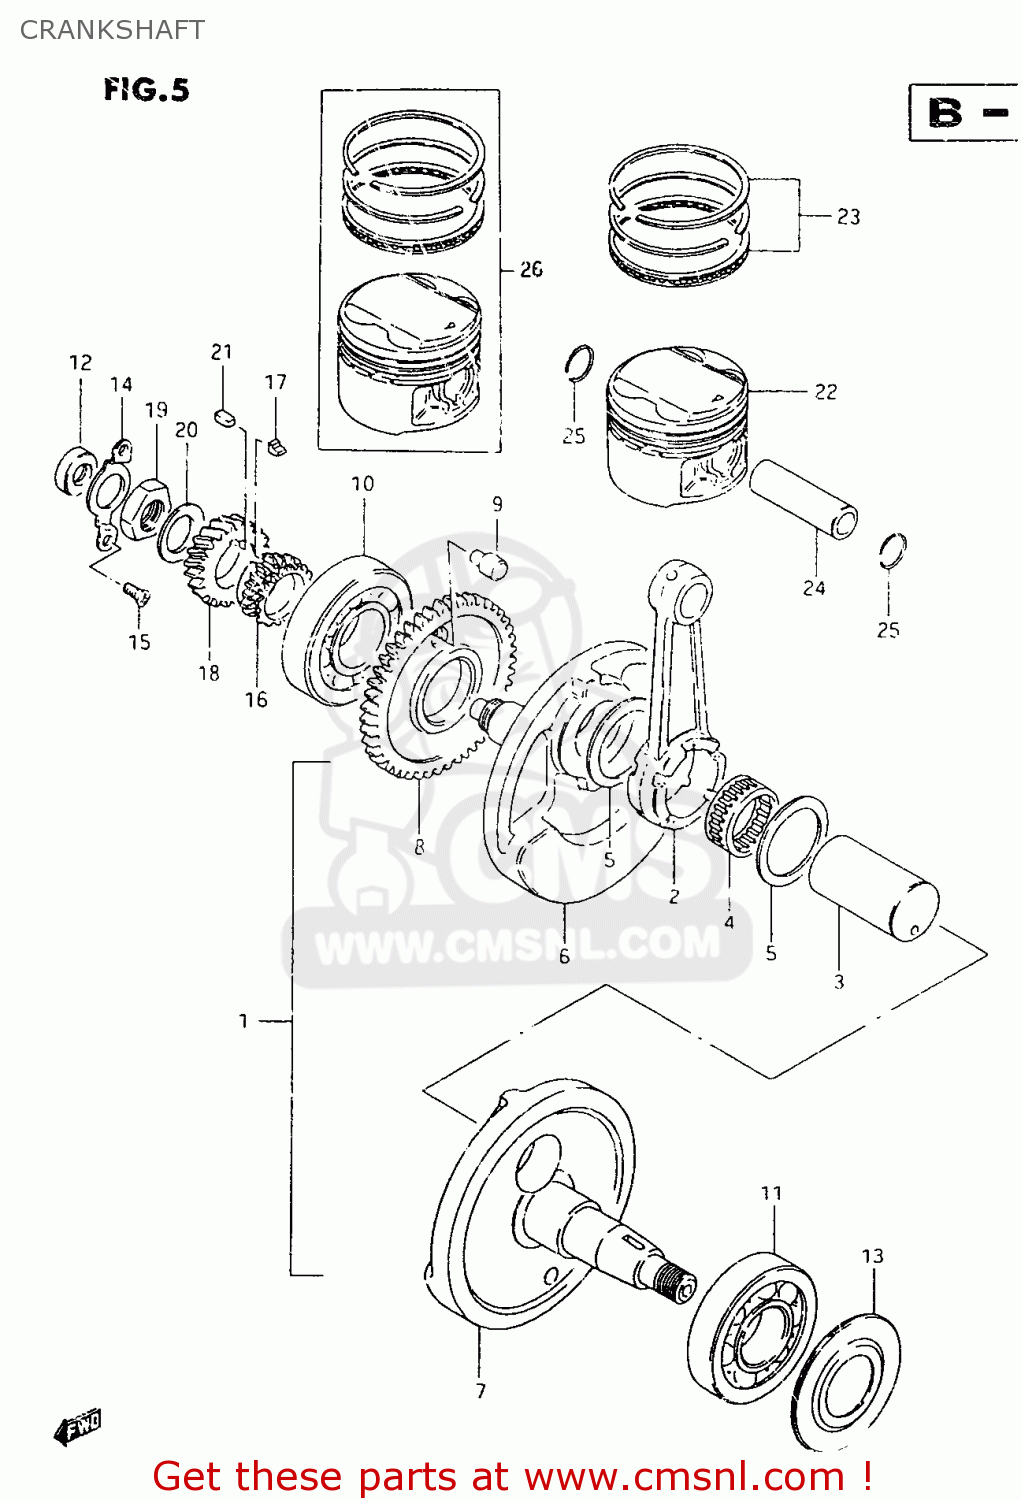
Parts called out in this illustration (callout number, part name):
1	CRANKSHAFT ASSEMBLY
2	ROD,CONNECTING
3	PIN,CRANK
4	BEARING(31X39X21)
5	WASHER(31X48.5X1)
6	CRANKSHAFT,R
7	CRANKSHAFT,LEFT
8	GEAR,CRANK BALANCER DRIVE
9	PIN
10	BEARING(30X72X19)
11	BEARING(35X80X21)
12	SEAL,OIL(14X26X6)
13	WASHER,CRANKSHAFT OIL SEALING
14	RETAINER,CRANKSHAFT BEARING,R
15	SCREW
16	SPROCKET,CAM CHAIN DRIVE(NT:21
17	KEY,SPROCKET
18	GEAR,PRIMARY DRIVE NO.21
19	NUT (20MM)
20	WASHER
21	KEY
22	PISTON (72.00MM)
23	RING SET,PISTON
24	PIN,PISTON
25	CIRCLIP,PISTON PIN
26	PISTON SET(OS:0.5)
